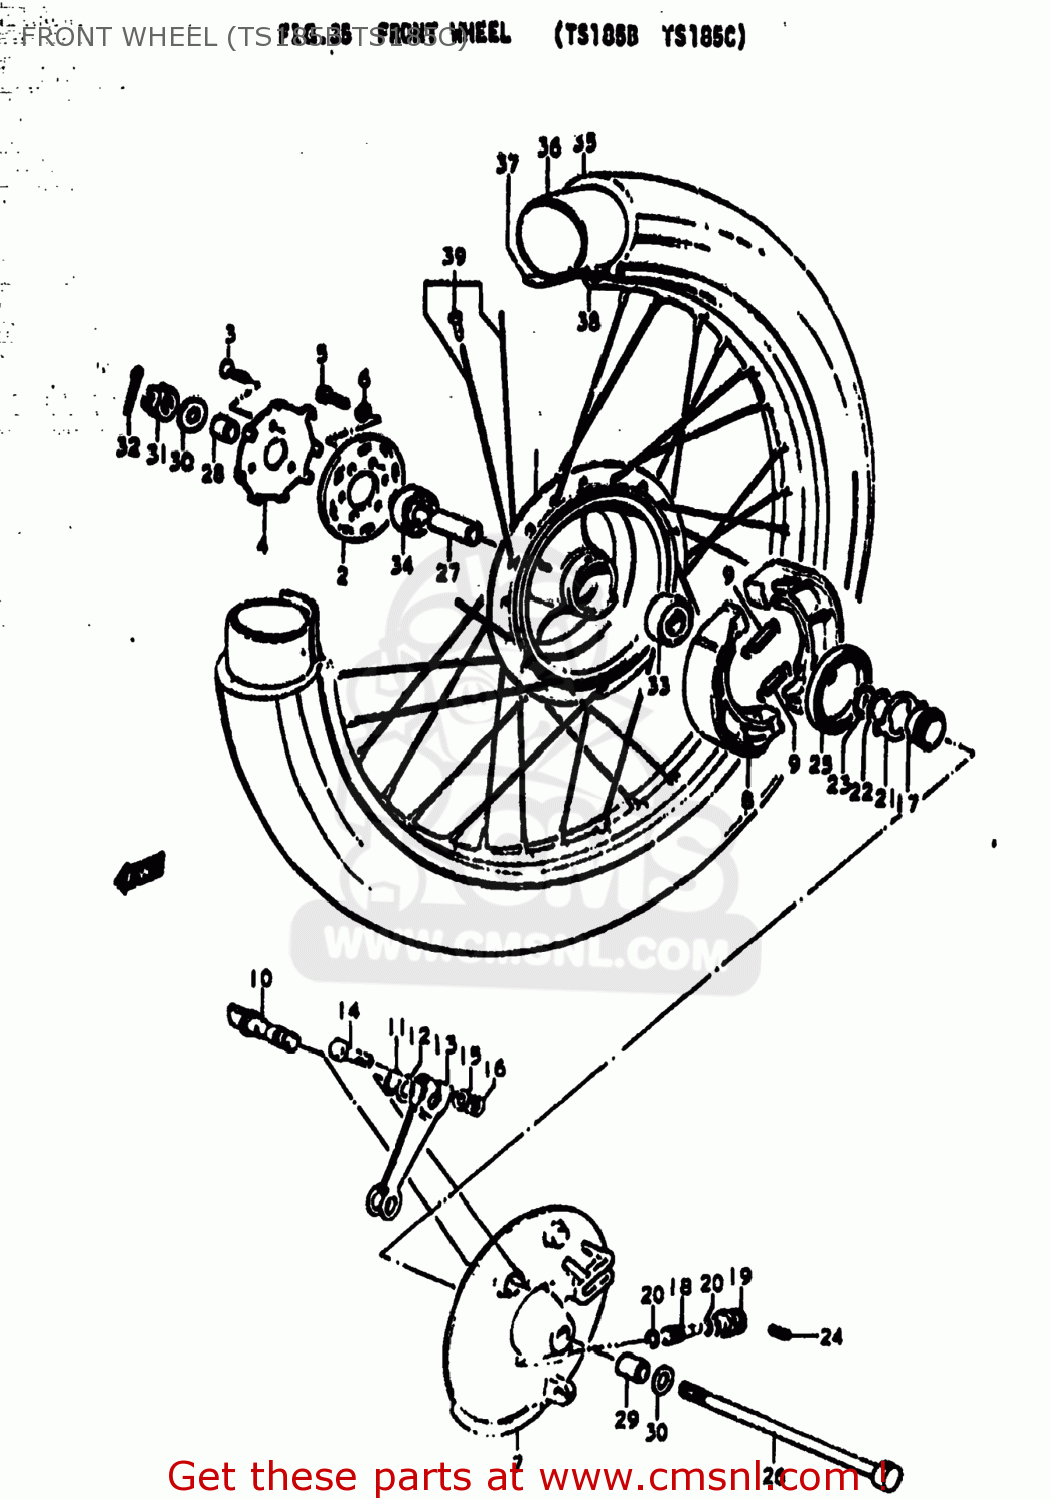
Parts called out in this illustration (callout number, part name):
1	HUB,FR WHEEL
2	FLANGE,FR HUB,R
3	SCREW
4	RETAINER,FR HUB BEARING,R
5	BOLT, UPPER
6	LOCK WASHER
7	PANEL,FRONT HUB
8	SHOE,BRAKE
9	SPRING(L:34)
10	CAM,FRONT BRAKE
11	O-RING (D:2.4 ID:13.8)
12	WASHER (14.5X22X1.6)
13	LEVER,FR BRAKE CAM
14	BOLT(6X35)
15	WASHER
16	NUT
17	GEAR,SPEEDOMETER
18	PINION,SPEEDOMETER
19	BUSH,METER GEAR OUTER
20	WASHER (5.1X9X0.4)
21	DRIVER,SPEEDOMETER GEAR
22	WASHER(18.5X24X1)
23	CIRCLIP
24	SCREW
25	OIL SEAL (43X58X7)
26	AXLE,REAR
27	SPACER (12.6X19X52)
28	SPACER (12.2X19X18.5)
29	SPACER(12X20X34.5)
30	WASHER
31	NUT 12MM
32	COTTER PIN
33	BEARING
34	BEARING, RH
35	TIRE,FRONT
36	TUBE
37	PROTECTOR,WHEEL,INNER
38	RIM,FRONT WHEEL
39	SPOKE SET,FRONT
